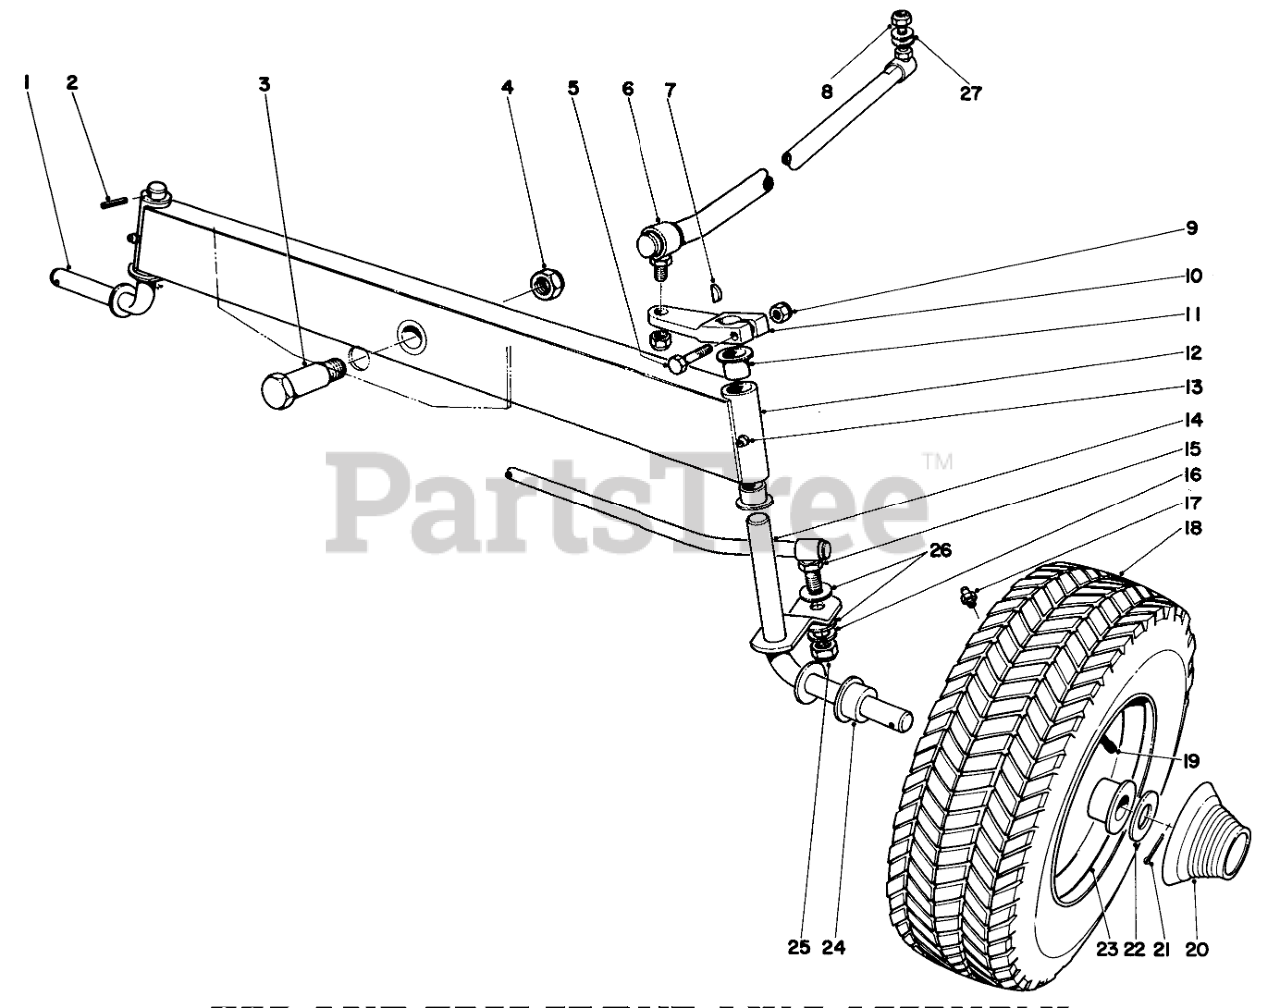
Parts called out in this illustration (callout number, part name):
1	Spindle
2	PIN-SPRING
3	Shoulder Bolt
5	SCREW-HH
6	Drag Link
7	KEY-WOODRUFF
8	Nut
10	Arm Drag Link
11	3/4IDX1LG FLANGE BSHG
12	Front Axle Incl. Ref. #11
13	Grease Fitting
14	Spindle L.H.
15	Tie Rod
16	WASHER-LOCK
17	FITTING-GREASE
19	Valve Stem
20	FRONT HUB CAP
21	PIN-COTTER
22	Washer
23	Rim
24	Bushing
25	Nut
26	WASHER
27	WASHER-FLAT
